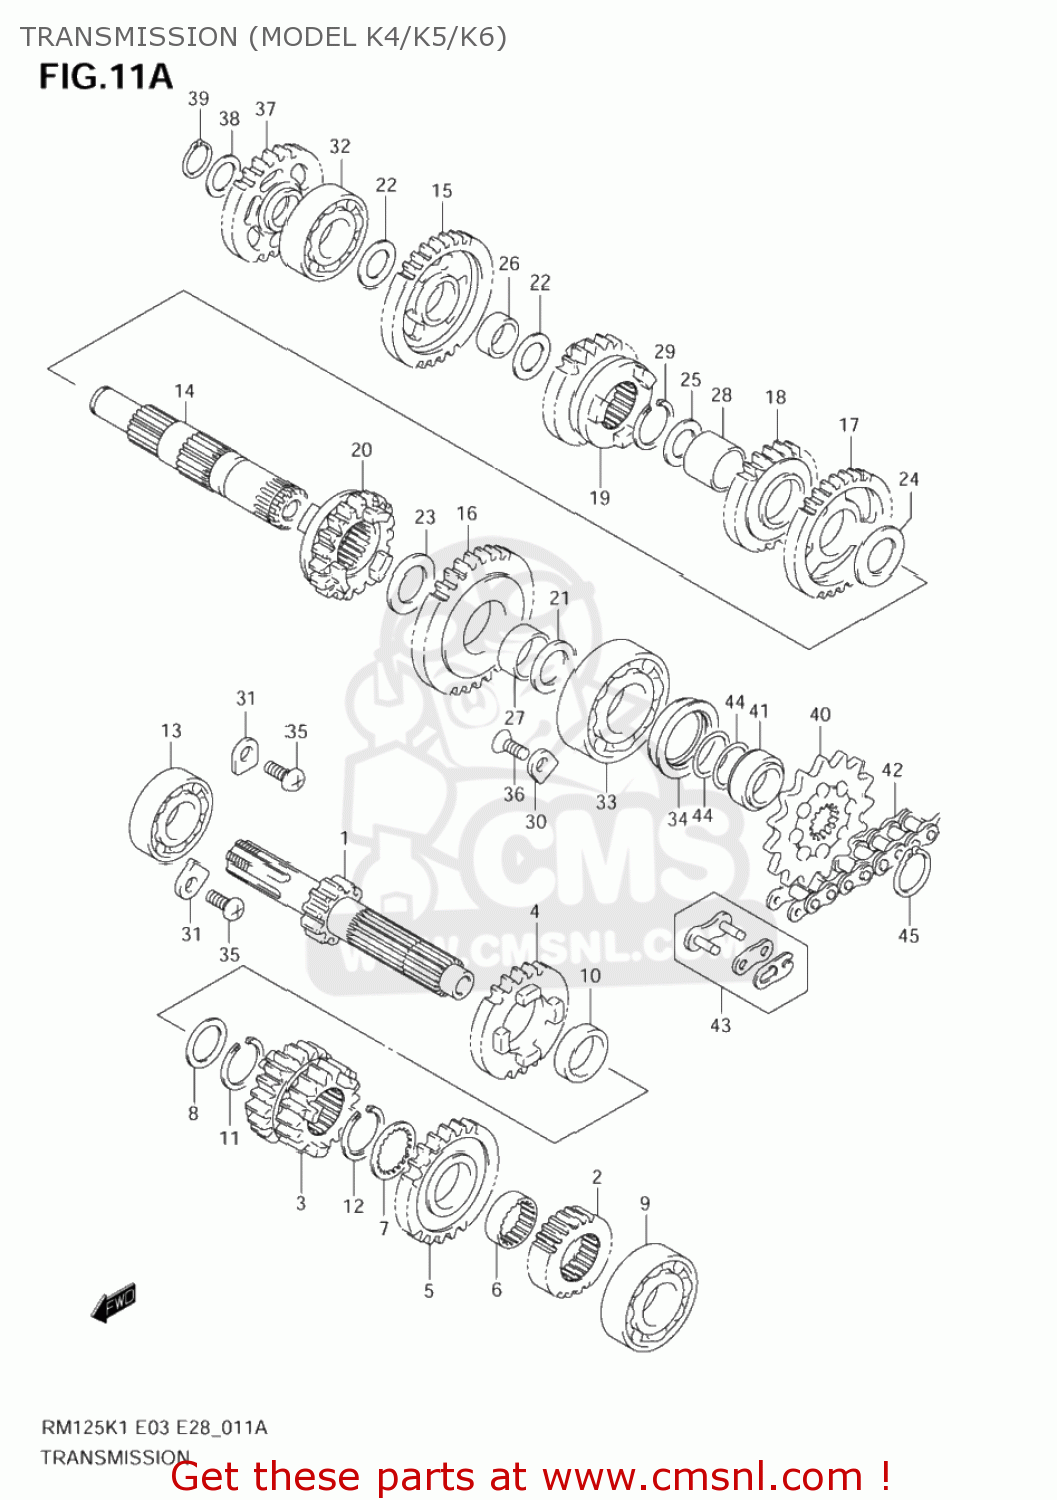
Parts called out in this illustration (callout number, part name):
1	SHAFT,COUNTER
2	GEAR,2ND DRIVE(NT:16)
3	GEAR,3RD & 4TH DRIVE(NT:18/20)
4	GEAR,5TH DRIVE(NT:19)
5	GEAR,6TH DRIVE(NT:20)
6	BUSH,6TH DRIVE GEAR
7	WASHER,LOCK
8	SHIM(22X28X1)
9	BEARING(17X40X9.5)
10	BUSH(22X26X9)
11	CIRCLIP
12	CIRCLIP
13	BEARING(20X47X12)
14	SHAFT,DRIVE
15	GEAR,1ST DRIVEN(NT:29)
16	GEAR,2ND DRIVEN(NT:27)
17	GEAR,3RD DRIVEN(NT:26)
18	GEAR,4TH DRIVEN(NT:24)
19	GEAR,5TH DRIVEN(NT:20)
20	GEAR,6TH DRIVE
21	WASHER(20X30X3)
22	SHIM(17X26X1)
23	SHIM(22X30X1)
24	SHIM(22X30X1)
25	SHIM(22X30X1)
26	BUSH(17X20X9)
27	BUSH(22X26X9)
28	BUSH(22X25X18)
29	CIRCLIP
30	RETAINER,COUNTER BEARING,R
31	RETAINER
32	BEARING(17X40X9.5)
33	BEARING(20X52X12.5)
34	SEAL,OIL(28X38X7.5)
35	SCREW
36	SCREW
37	GEAR,KICK STARTER IDLE
38	SHIM(17X24X0.5)
39	CIRCLIP,17MM
40	SPROCKET,ENGINE
41	SPACER,ENGINE SPROCKET
42	CHAIN ASSY,DRI
43	JOINT SET,CHAIN
44	O RING(D:1.9,ID:19.8)
45	CIRCLIP
